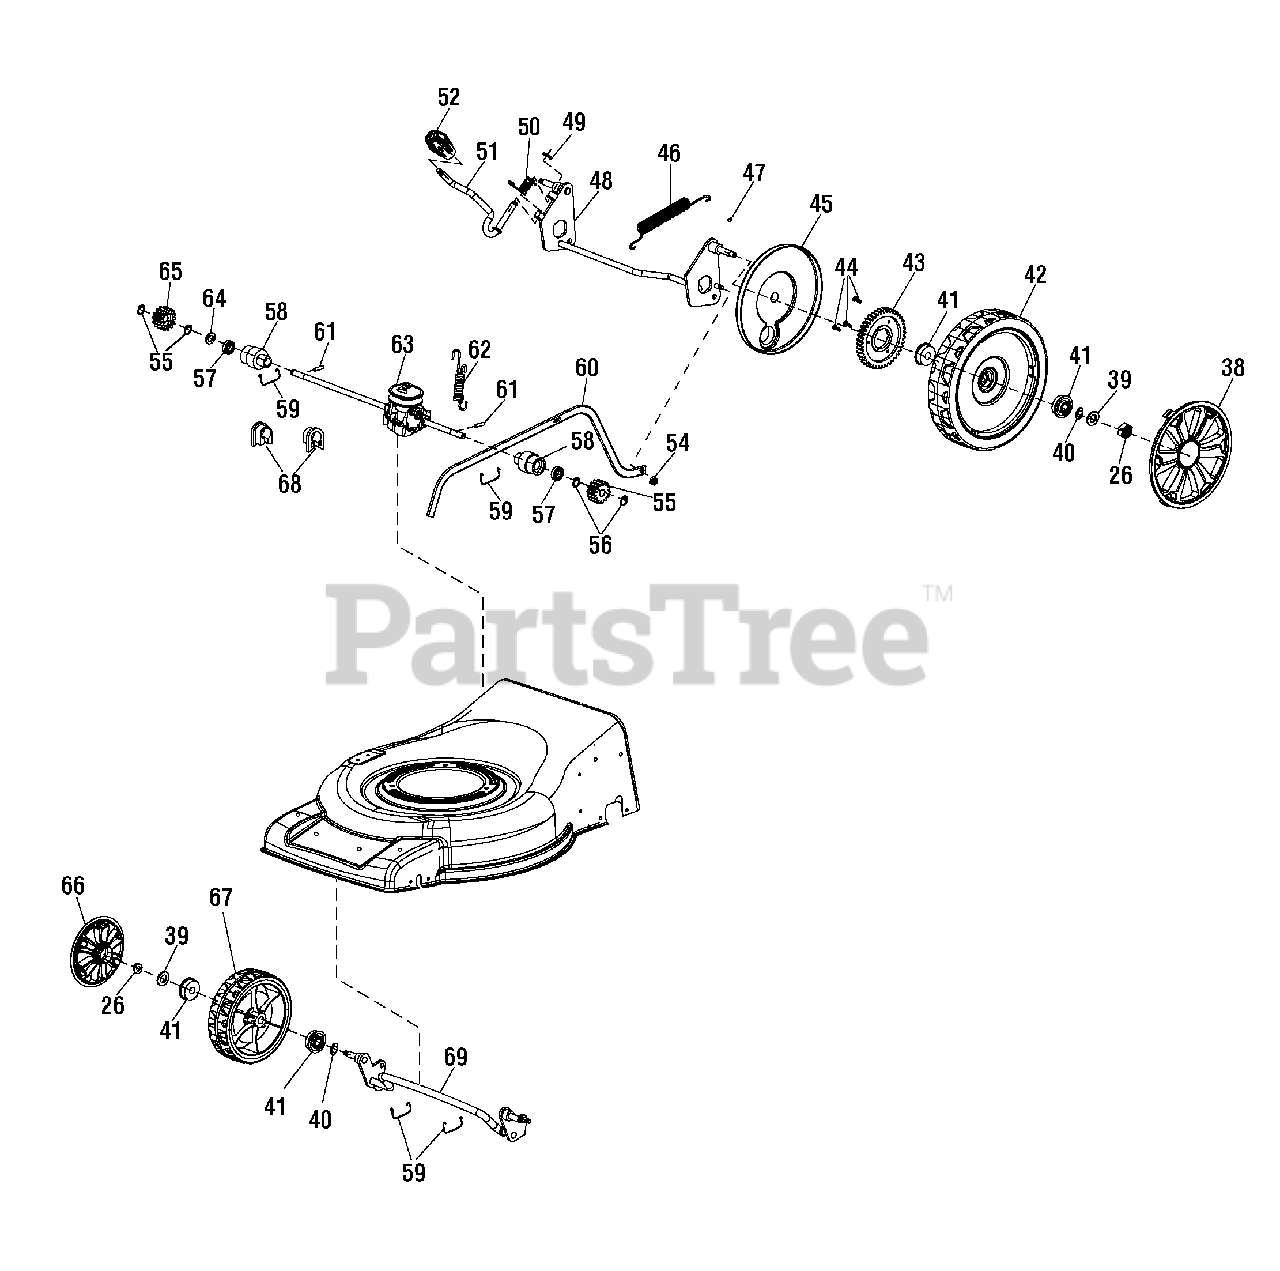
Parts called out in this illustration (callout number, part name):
26	NUT, Hex, M8
38	HUBCAP, Rear
39	WASHER, Plain, 8
40	WASHER, Wave
41	BALL BEARING
42	WHEEL, Rear
43	DRIVE GEAR, Right
44	SCREW, ST 4.2 x 16F
45	DUST COVER, Rear
46	SPRING, Connecting Rod
47	CAP, Spring
48	AXLE ASSEMBLY, Rear
49	WASHER, Split, 8
50	SPRING, Height Adjust
52	KNOB, Height Adjust
53	BOLT, Self Tapping
54	NUT, Self Lock, M6
56	DRIVE GEAR
57	BALL BEARING, 61901-2Z
58	BUSHING
59	CLIP, Axle
62	PUMP
63	GEARBOX ASSEMBLY
65	DRIVE GEAR
66	HUBCAP, Front
67	WHEEL, Front
68	BUSHING, Shaft
